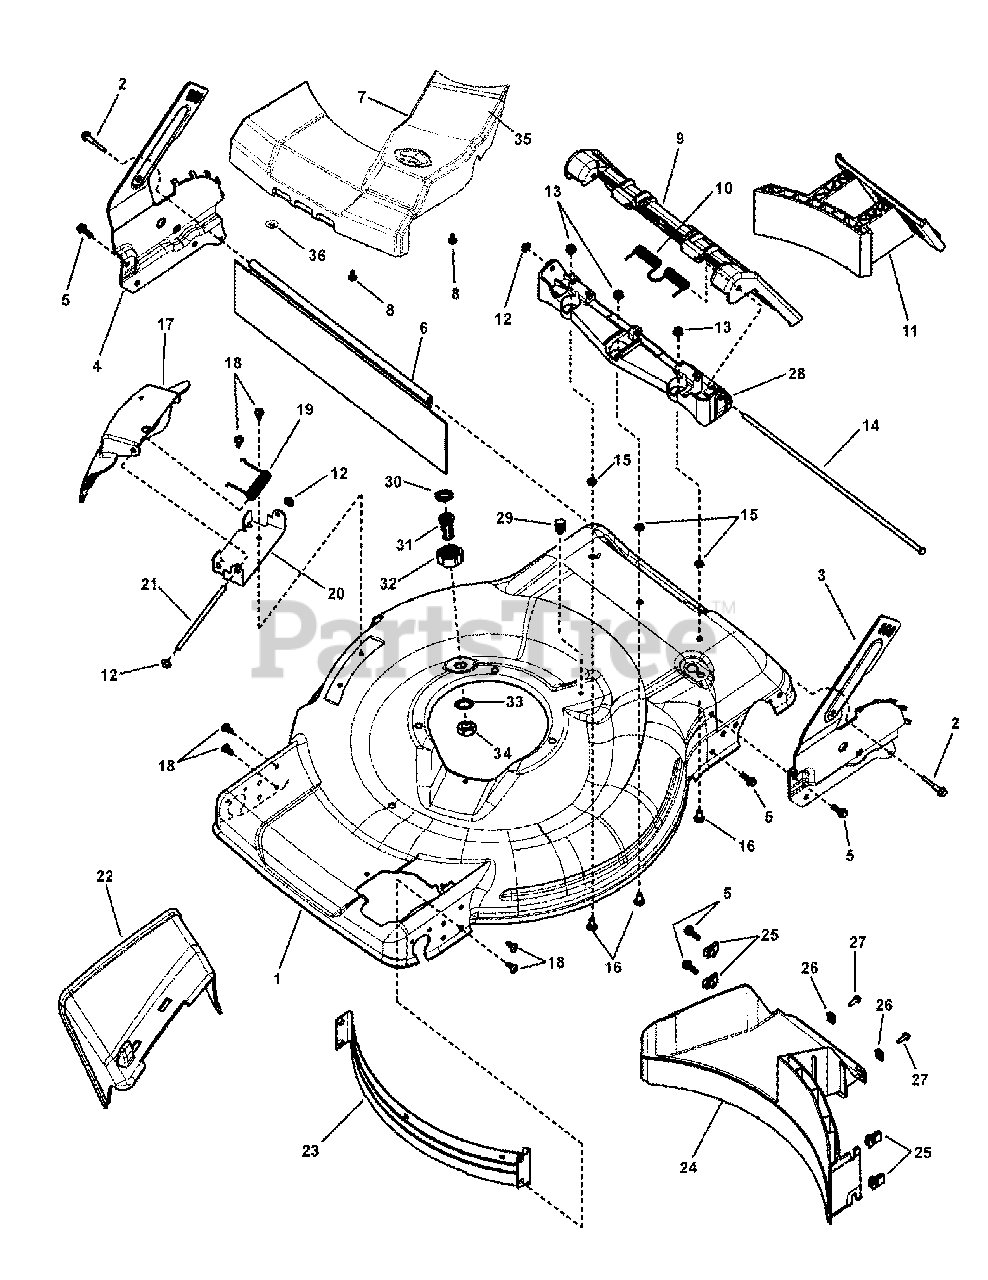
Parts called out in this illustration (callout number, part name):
1	DECK, 22", Front Wheel Drive, Washout
2	BOLT, Drag Shield, 1/4-20 x 1-1/2"
3	BRACKET, Lower Handle, LH, Hi-Wheel
4	BRACKET, Lower Handle, RH, Hi-Wheel
5	BOLT, 1/4-20 x 3/4" Hex Flange Lock, GR 5
6	GUARD, Rear, 22"
7	ASSEMBLY, Belt Cover
8	SCREW, 4.8 x 1.59 x 13mm, Round Washer Head Hi-Lo (Torx)
9	DOOR, Rear Discharge
10	SPRING, Torsion, Rear Door
11	PLUG, Mulching, 22" Deck
12	PUSHNUT, 1/4"
13	NUT, 1/4-20 Hex Flange Lock
14	ROD, Pivot, Rear Door
15	RETAINER, 1/4" Bolt
16	BOLT, 1/4-20 x 5/8" Flat Head Square Neck, GR 5
17	COVER, Mulching
18	SCREW, 1/4-20 x .550" Pan Head Torx (T-30)
19	CHUTE SPRING, Torsion
20	BRACKET, Chute
21	ROD, Pivot
22	CHUTE, Side Discharge, 22" WBM
23	BAFFLE, Front
24	REAR BAFFLE, Front Wheel Drive, WBM
25	U-NUT, 1/4-20
26	SPEED NUT, #10-24 Retainer w/Extrusion
27	SCREW, #10-24 x 5/8" Hex Washer Face self-Tap, GR 5
28	DOOR HINGE, Rear Discharge
29	PLUG, Panel, 1/4" x .61 Long, Black
30	WASHER, Hose
31	ADAPTOR, Washout Port, WBM
32	COUPLING, Hose
33	WASHER, 5/8" Internal Tooth Lock
34	NUT, 5/8-11, NC-2B Black Hex Jam
35	PATCH, Heat Cover
36	NUT, Push, 3/16
